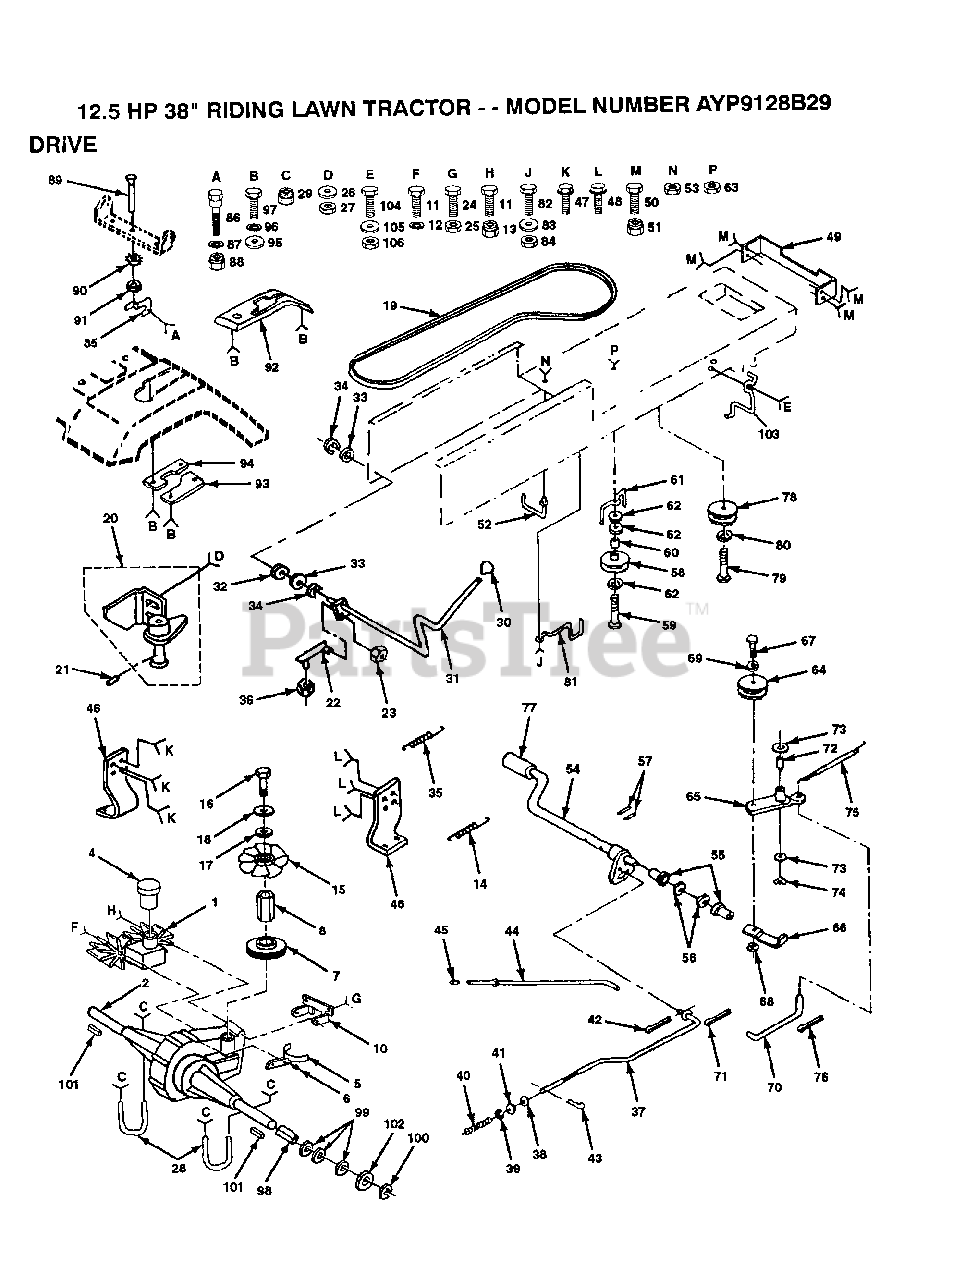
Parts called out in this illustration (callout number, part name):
1	PUMP.BDU-10S-114
2	TRANSAXLE.AGRIFAB
4	PUMP.2003081.
5	"GRD ASS'Y,BELT"
7	"PULLEY,TRANSAXLE"
8	STANDOFF
10	BRACKET
11	BOLT
12	LOCKWASHER
17	WASHER
18	LOCKWASHER
20	"FRICTION,PACK ASS"
21	"PIN,ROLL METRIC"
22	"LINK,PUMP CONTROL"
23	NUT WIZLOC T
26	WASHER
28	U BOLT
30	KNOB T (1/2-HOLE)
31	"LEVER,CONTROL"
32	"BUSHING,PIVOT"
33	"WSHER,SHIM"
34	RING T
35	"SPRING,EXTENTION"
36	NUT WIZLOC T
38	NUT
39	NUT
40	SPRING ROD LT
41	WASHER
42	SPRING.RETAINER
43	RETAINER M
44	BRAKE PARK ROD
45	PLUNGER CAP T
46	BRKT TRANSAXLE
47	SCREW GTV
48	SCREW
49	PLATE TRANS SUPT
52	"KEEPER,CENTERSPAN"
55	NYLON BEARING
56	WASHER LT
58	PULLEY.IDLER.FLAT
59	BOLT
60	SPACER T
61	BELT KEEPER LT
62	WASHER
65	ARM IDLER
66	RETAIN BELT
69	WASHER
70	"LINK, CLUTCH T"
71	COTTER PIN
72	"LY, BEARING"
73	WASHER LT
74	KLIP RING
75	"SPRING, RETURN LT"
76	COTTER PIN
77	PEDAL COVER T
79	BOLT
80	LOCKWASHER
81	KEEPER.BELT.ENG.L
82	BOLT
83	WASHER
85	"ARM,BYPASS CONTRO"
86	BOLT T
87	WASHER T
89	CONTROL BYPASS
90	LOCKWASHER
92	"CONSOLE,SHIFT FEN"
93	"PLATE,NEUTRAL RH"
94	"PLATE,NEUTRAL LH"
95	WASHER PM
96	LOCKWASHER
98	SPACER SPLIT
99	WASHER
100	E-RING LT
101	SQUARE KEY
102	WASHER
103	GUIDE BLT DR MWR
104	BOLT
105	WASHER
